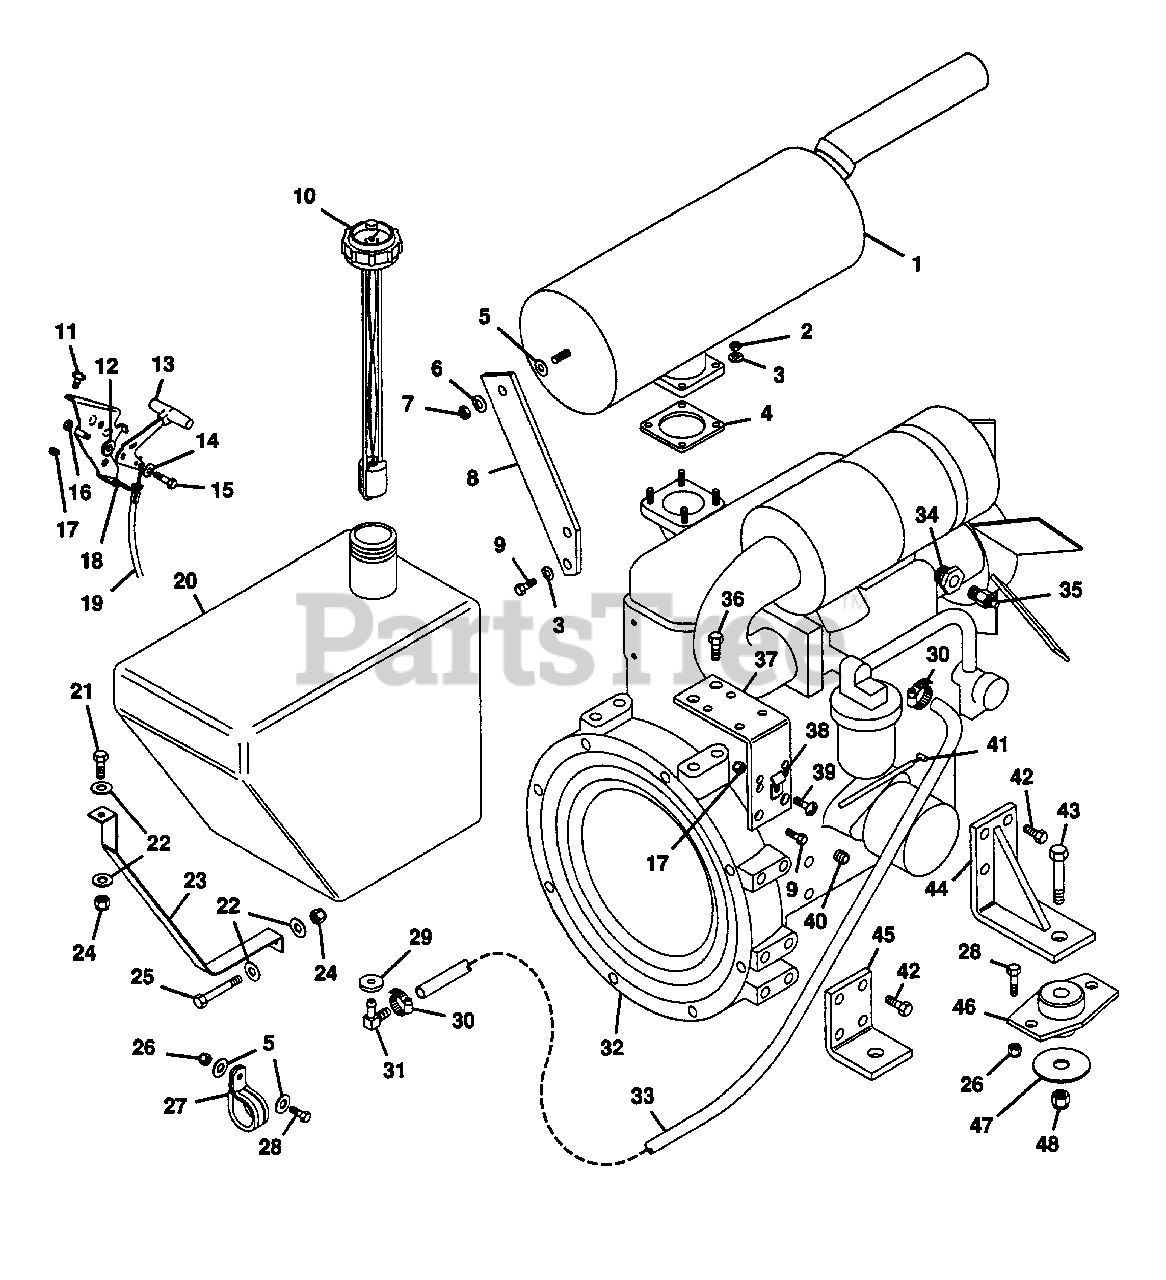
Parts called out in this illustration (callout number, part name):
1	Muffler, Yanmar
2	Nut, Hex M8 x 1.25
3	Washer, Lock 5/16 Reg.
4	Gasket, Exhaust
5	Washer, Flat .406x.812x.065
6	Washer, Lock 3/8 Reg.
7	Nut, Hex 3/8-16
8	Brace, Muffler
9	Bolt, Hex M8 x 1.25 16mm
10	Gauge, Fuel
11	Screw, Machine 10-24x.50 PHD
12	Washer, Friction
13	Assembly, Knob and Lever
14	Washer, Spring
15	Bolt, Hex 1/4-28x.75
16	Nut, Lock 1/4-28
17	Nut, Lock 10-24
18	Bracket, Mounting L.H.
19	Assembly, Conduit
20	Tank, Fuel
21	Bolt, Hex 5/16-18x2.00
22	Washer, Flat .344x.688x.065
23	Strap, Gas Tank
24	Nut, Lock 5/16-18
25	Bolt, Hex 5/16-18x.75
26	Nut, Lock 3/8-16
27	Clamp, Steel 1.00
28	Bolt, Hex 3/8-16x1.00
29	Bush., Flg. .375x1.06x.625 Rb.
30	Clamp, Hose
31	Fitting, Tank
32	Engine, Yanmar
33	Fuel Line .5 OD x .25 ID,
34	Adapter, Temperature Sender
35	Sender, Temperature
36	Bolt, Hex M10 x 1.5 16mm
37	Bracket, Control
38	Clip
39	Screw, Machine 10-24x.625 PHD
40	Plug, PT 1/4
41	Clamp, Swivel Wire
42	Bolt, Hex M10 x 1.5 20mm
43	Bolt, Hex 1/2-13x2.75
44	Weldment, Engine Mount
45	Mount, Engine
46	Mount, Engine
47	Washer, Snubbing
48	Nut, Lock 1/2-13
